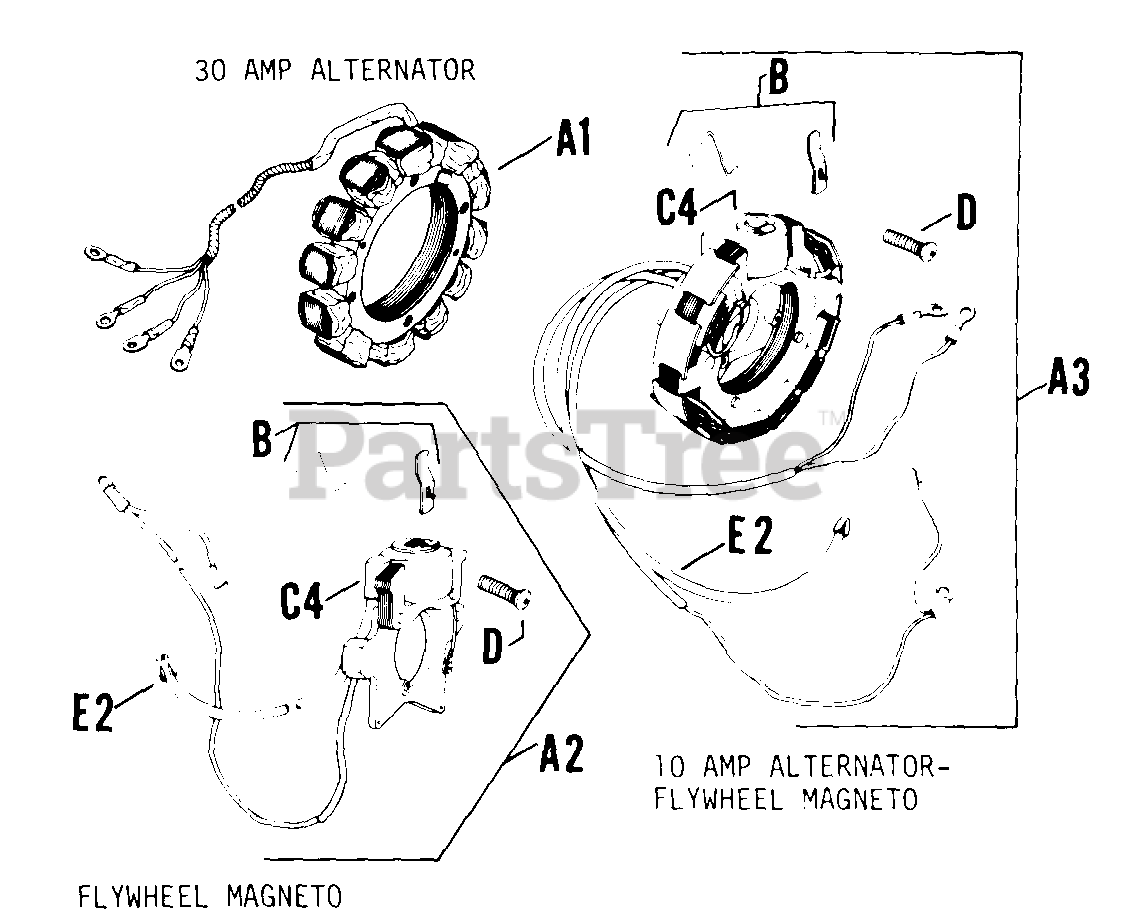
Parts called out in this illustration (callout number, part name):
A2	STATOR - DISCONTINUED
B	KIT, CLIP - DISCONTINUED
C4	COIL - USE 47 755 20
E2	LEAD - DISCONTINUED
